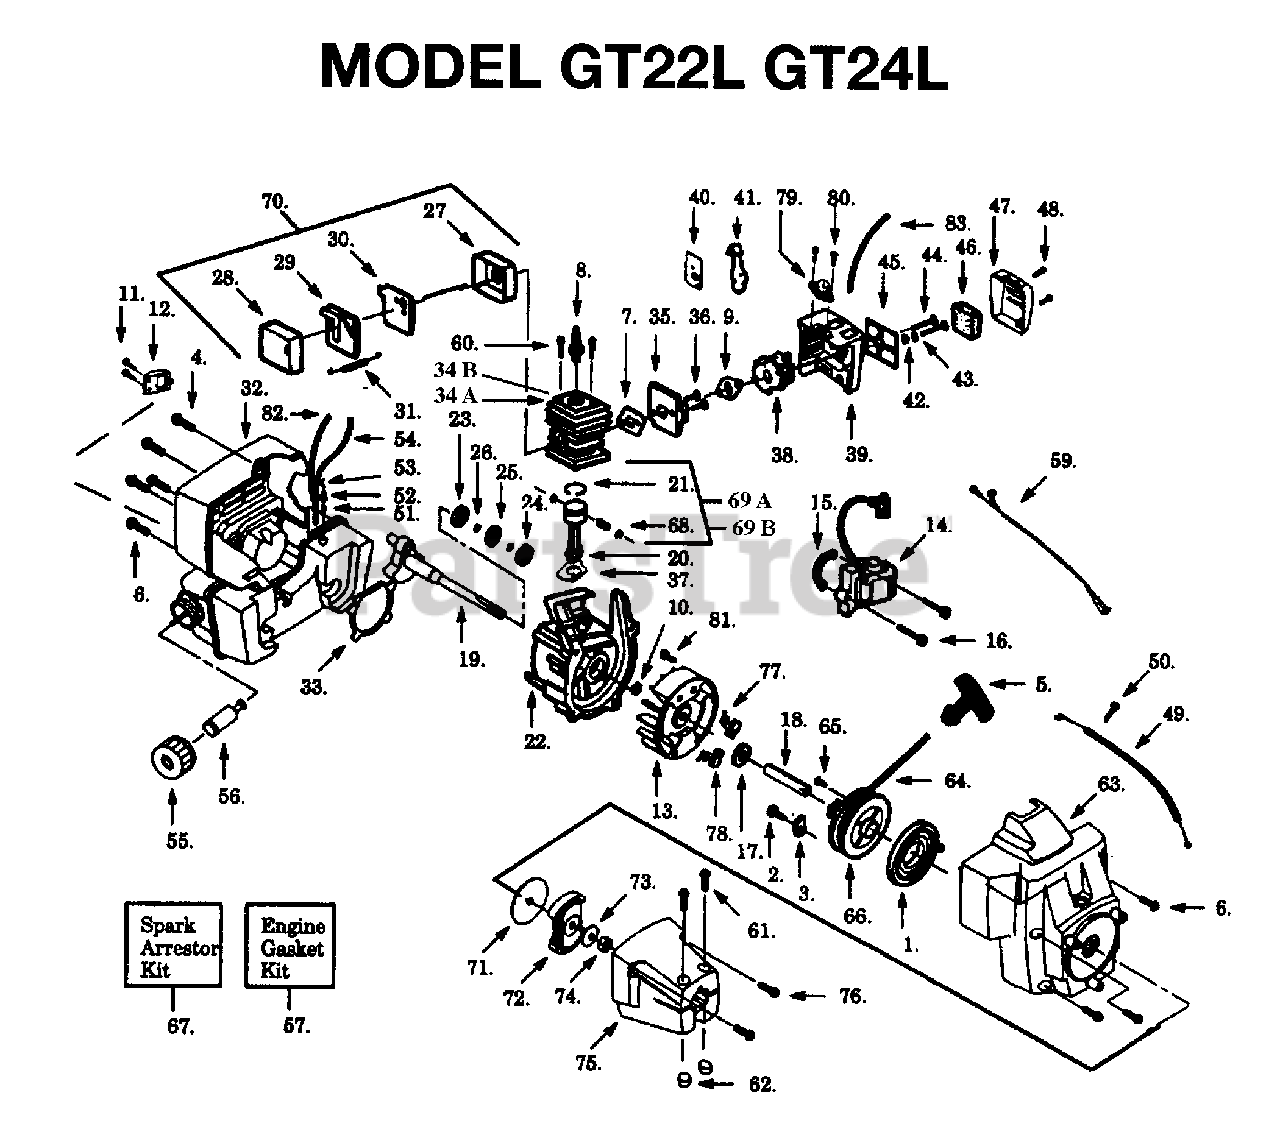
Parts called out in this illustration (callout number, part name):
1	SPRING-STARTER
2	SCREW 8-16 X 9/16 (PLAS
5	HANDLE-STARTER
6	SCREW - SHROUD
8	SPARK PLUG (RCJ-8Y) NLA
9	GASKET - CARBURETOR
11	SCREW-8-18 X 5/18(RECES
12	MUFFLER GUARD
13	FLYWHEEL
14	IGNITION MODULE
15	SPACER - IGNITION MODULE
19	CRANKSHAFT ASSEMBLY
20	CONNECTING ROD ASSEMBLY
21	PISTON RING
22	CRANKCASE ASSY
23	BEARING
25	SEALING RING
26	RETAINING RING
27	MUFFLER BODY
28	MUFFLER COVER
29	MUFFLER BAFFLE - EXIT
30	MUFFLER BAFFLE - FIRST
31	MUFFLER SPRING
33	GASKET, CRANKCASE
34A	CYLINDER
35	CARB. ADAPTER
36	SCREW - CARB. ADAPTOR
37	GASKET - CYLINDER
38	CARBURETOR
40	CHOKE PLATE
41	CHOKE SHUTTER
43	CHOKE SPACER
45	FILTER PLATE
46	AIR FILTER FOAM
47	AIR FILTER COVER
48	SCREW - THROTTLE HOUSING
51	VALVE-CHECK (DUCKBILL)
55	CAP ASSY W/ RETAINER
56	FUEL PICK UP ASSY
59	LEAD WIRE ASSEMBLY
61	SCREW - PINCH CLAMP
62	LOCKNUT-HEX 10-24
66	STARTER PULLEY KIT
67	KIT-SPARK ARRESTOR (OLD STYLE)
68	WRIST PIN RET.
69A	PISTON KIT
71	FRICTION DISC,CLUTCH 36/41
72	CLUTCH ASSEMBLY KIT
73	WASHER FLAT
76	SCREW-10-14 X 13/16 (PL
79	AIR PURGE BUBBLE
80	SCREW - PRIMER ASSEMBLY
82	FUEL LINE - PRIM/TNK
